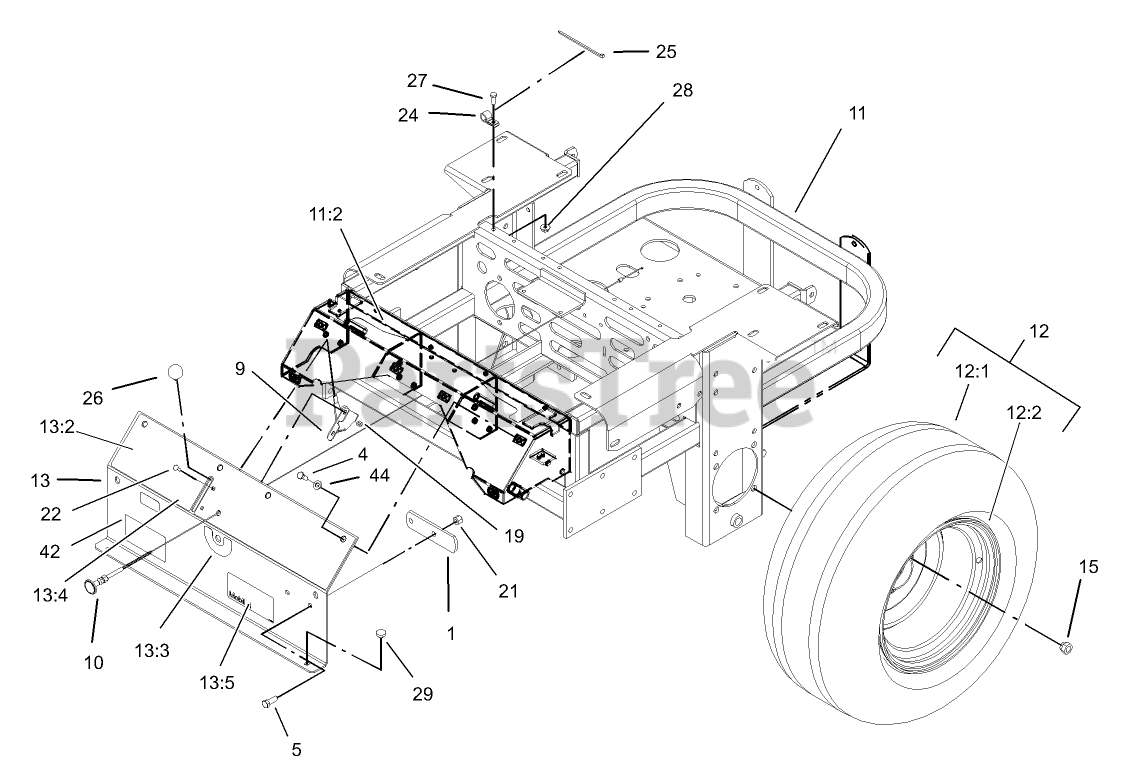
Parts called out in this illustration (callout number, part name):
1	STOP-BRAKE, PARK
4	SCREW-HH
5	SCREW-HH
9	THROTTLE CABLE ASM
10	CONTROL-CHOKE
11	Main Frame ASM
11:2	DECAL-CONSOLE, TOP
12	WHEEL AND TIRE ASM
12:2	WHEEL RIM
13	Console ASM
13:2	Decal-Control Panel
13:3	DECAL-VALVE, FUEL
13:4	DECAL-PROTECTION, EAR
13:5	DECAL-MOBIL 1
15	NUT-LUG
19	NUT-LOCK, NI
21	NUT-LOCK, NI
22	BOLT-CARR
24	CLIP-LOOM
25	TIE-PLASTIC
26	KNOB-BALL
27	SCREW-HH
28	NUT-HF
29	BUMPER
42	Decal-Z287l
44	WASHER-PLAIN
